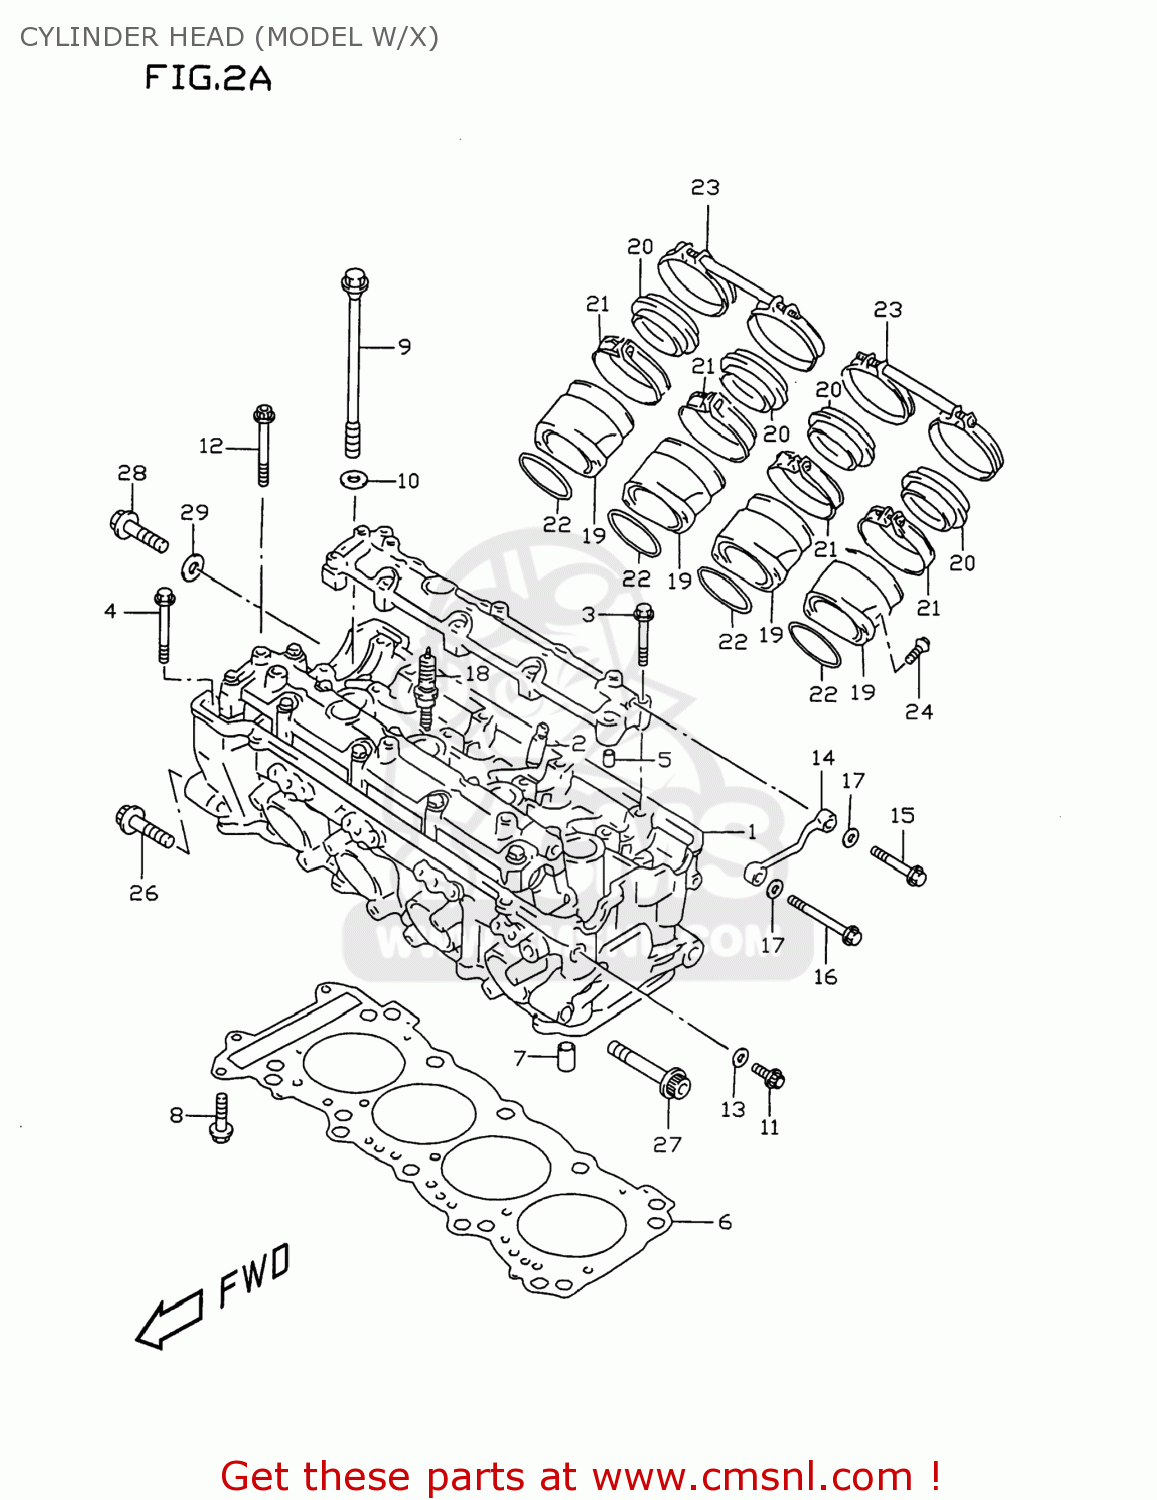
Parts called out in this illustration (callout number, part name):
1	HEAD ASSY,CYLINDER
2	GUIDE,VALVE
3	BOLT(6X39)
4	BOLT(6X45)
5	PIN(6.2X8X16)
6	GASKET,CYLINDER HEAD (T
7	PIN
8	BOLT
9	BOLT(10X160)
10	WASHER(10.5X19X2)
11	BOLT
12	BOLT,CYL.OIL P
13	GASKET(5.8X13X1.2) (NAS)
14	PIPE,CYLINDER HEAD OIL
15	BOLT
16	BOLT (6X45)
17	WASHER
18	PLUG,SPARK(CR8E)
19	PIPE,INTAKE NO.1
20	PIPE,INTAKE NO.2
21	CLAMP
22	O RING(D:2.4,ID:44)
23	CLAMP,INTAKE PIPE
24	BOLT(6X16)
25	BOLT
26	BOLT
27	BOLT,CYL HEAD SIDE FACE
28	WASHER,HEAD COVER
